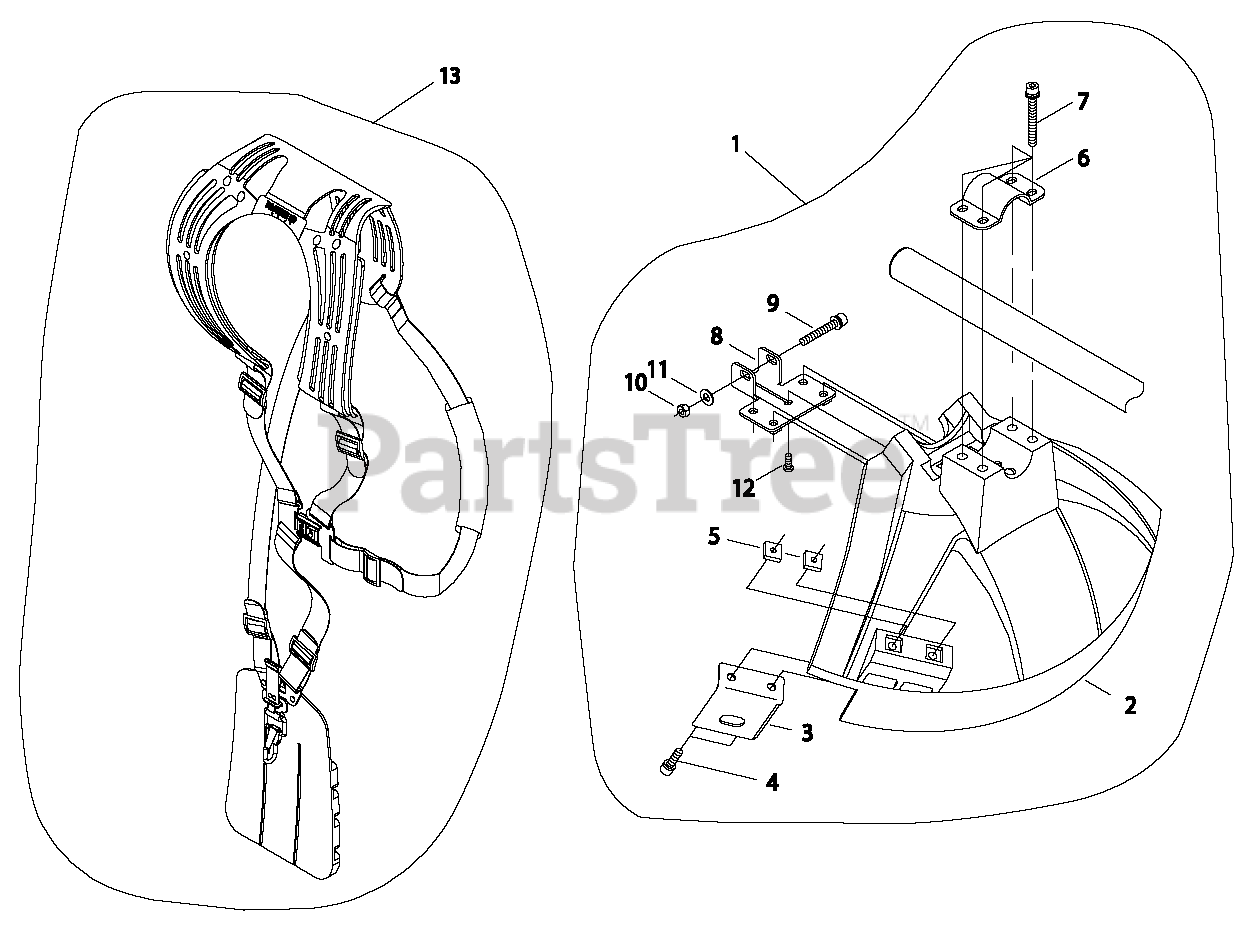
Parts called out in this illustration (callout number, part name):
1	DEBRIS SHIELD ASSY
2	SHIELD, DEBRIS - BLACK
3	KNIFE, TRIMMER LINE
4	SCREW - 5X16
5	NUT - 5
6	CLAMP - UPPER
7	SCREW - 5X45
8	CLAMP - LOWER
9	SCREW - 6X40
10	LOCKNUT - 6
11	WASHER - 6
12	SCREW
13	HARNESS ASSY
